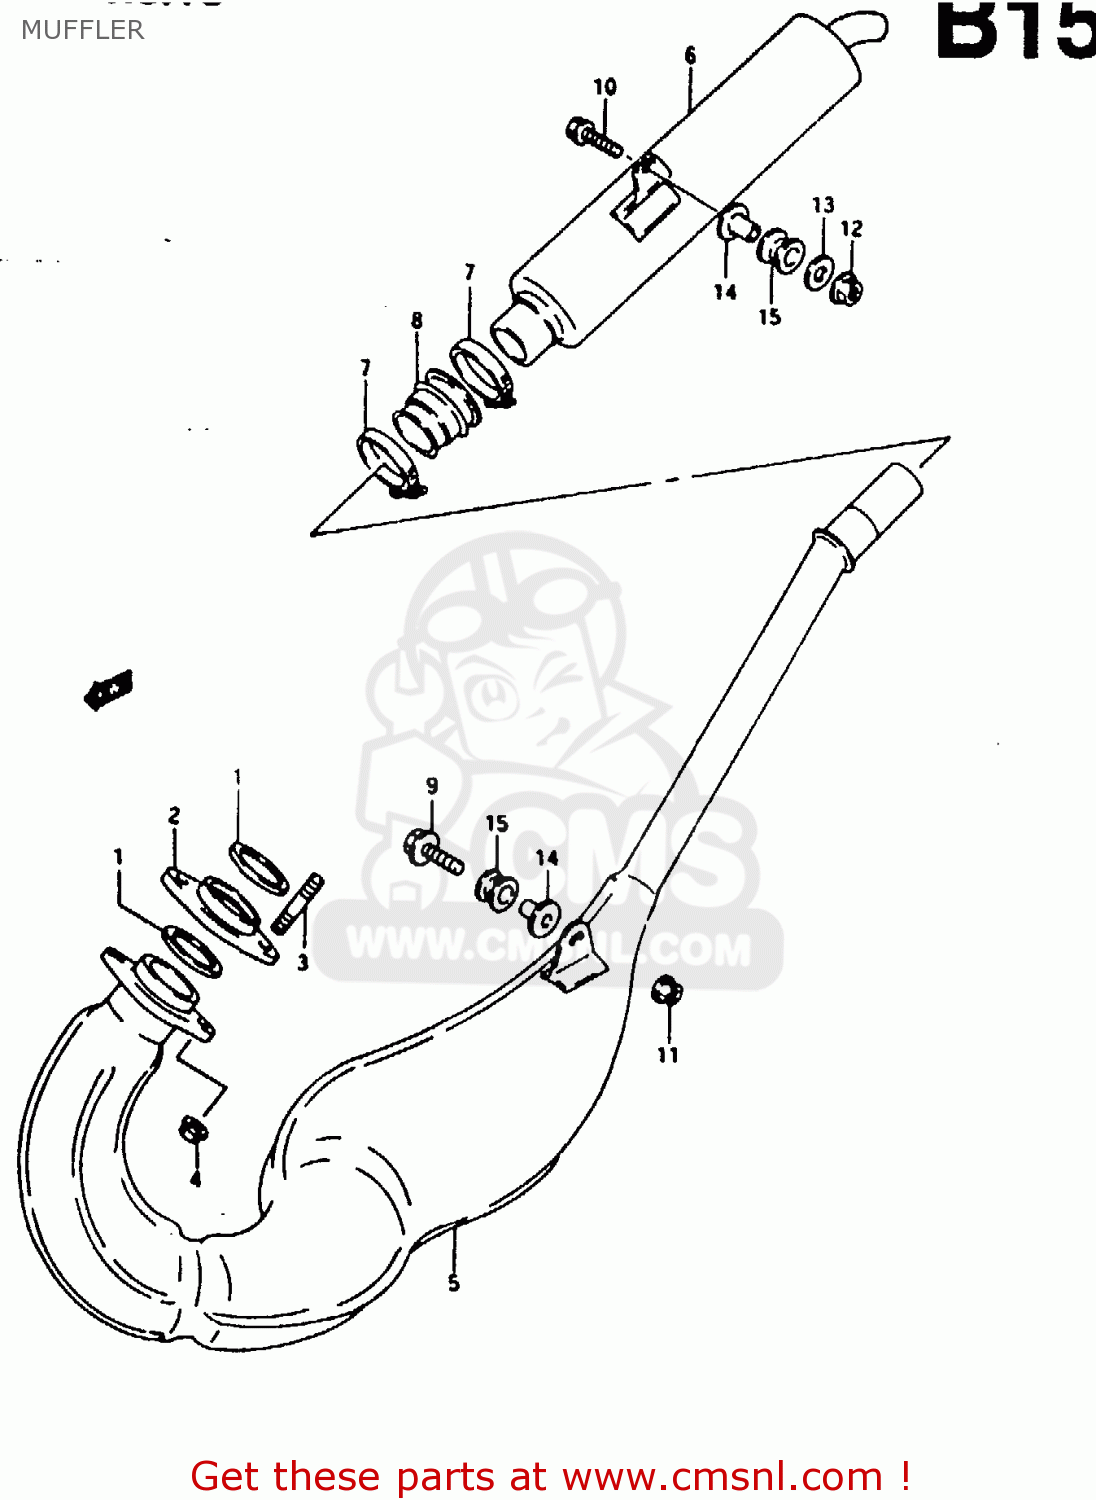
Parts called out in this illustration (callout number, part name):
1	GASKET,EXHAUST PIPE (NAS)
2	FLANGE,EXHAUST FITING
3	STUD BOLT
4	NUT
5	BODY, MUFFLER, 1ST
6	MUFFLER ASSY, 2ND
7	CLAMP
8	CONNECTOR,2ND MUFFLER
9	BOLT 8X35
10	BOLT
11	NUT
12	NUT
13	WASHER
14	SPACER(8.6X12X17.5)
15	CUSHION
